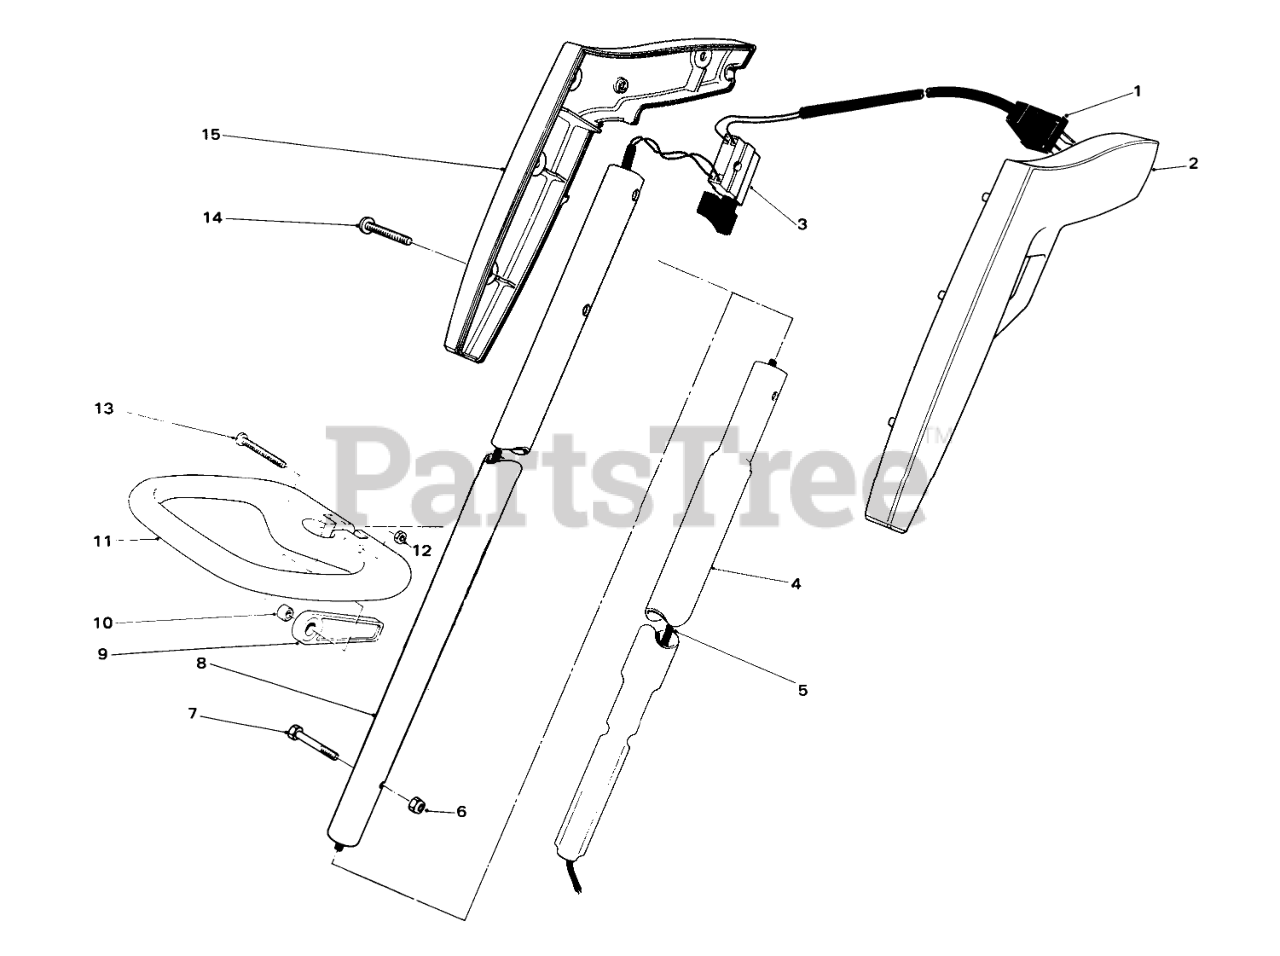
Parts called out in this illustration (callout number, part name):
1	Power Cord
2	Grip L.H.
3	SWITCH SINGLE SPEED
4	Tube-Lower
5	Wire Harness
6	NUT-LOCK, NI
7	HEX HD MACHINE SCREW
8	Tube-Upper
9	Cam Lock
10	Spacer
11	Support Handle
12	NUT-HEX
13	Screw
14	Screw
15	R.H. GRIP
